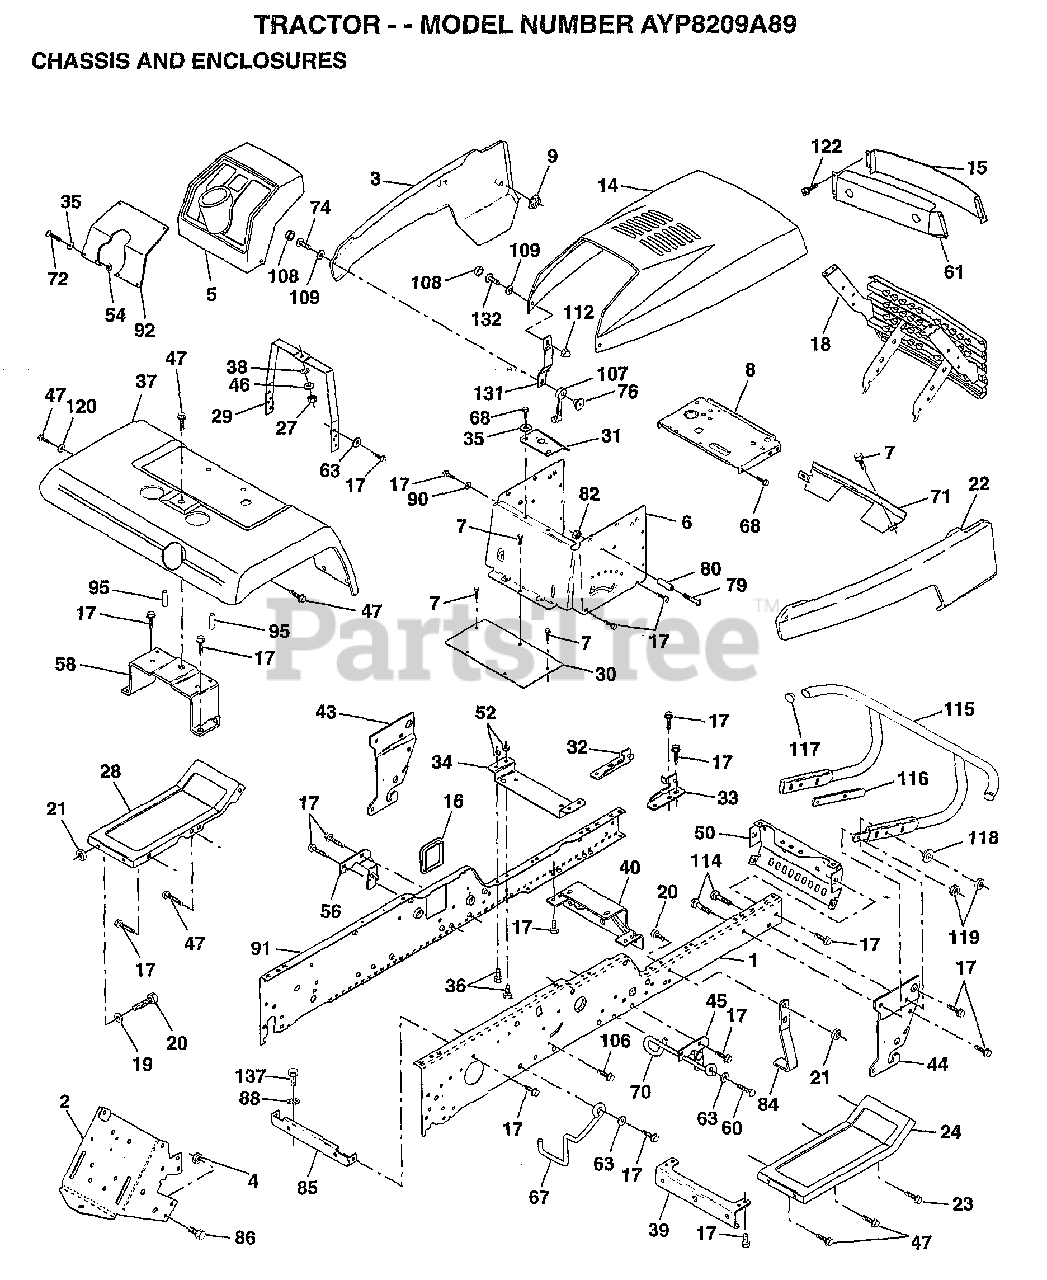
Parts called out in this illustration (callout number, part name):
1	"RAIL,FRAME RH"
2	DRAWBAR GT
3	"PANEL,ASM SIDE LH"
4	NUT GTV
5	DASHBOARD BLACK
6	DASH LOWER
7	SCREW
8	SUPPORT.DASH.BTRY
9	PAL NUT LT
14	"HOOD ASM.,PNT"
15	LENS.BAR.CLEAR
16	COVER ACCESS
17	SCREW
19	WASHER
20	BOLT
22	PANEL ASM.SIDE RH
23	SCREW GTV
24	FOOTREST.RH.LT/GT
28	FOOTREST.LT.LT/GT
29	DASH.SUPT.YP/HUSQ
30	SADDLE.SCR.6SP
31	BRKT SUPT 1-PC VG
32	BRACKET ASM FRAME
33	BRACKET ASM FRAME
34	BRACKET.ENG.SUPT.
35	WASHER
36	BOLT
37	"FENDER,RH"
38	LOCKWASHER
39	BRACKET.AXLE.FRT.
40	"BRKT SUPPORT,AXLE"
43	BRACKET.SUS.FT.LH
44	BRACKET.SUS.FT.RH
45	BRACKET.SUSP.RH.
46	WASHER PM
47	SCREW LT
50	"BRKT CHASSIS,FRNT"
56	BRACKET.SUSP.LH.
58	BRKT.ASM.FENDER
60	SCREW
61	BEZEL.ASM.
63	WASHER
67	"GUIDE BELT, T/A"
68	SCREW LT
70	GUIDE.BELT.MID.SP
72	SCREW
74	SCREW
76	WELDNUT
79	SCREW
80	SPACER LT
84	STOP.OVER.CENTER
85	BRACKET.SUPT.TRAN
86	BOLT
88	LOCKWASHER
90	LOCKWASHER
91	"RAIL FRAME,LH"
92	"PLATE DASH,SLKSCR"
95	NUT-PUSH YT
107	HOOD LATCH T
108	SNAP CAP LT
109	WASHER LT
112	ACORN NUT RB
114	BOLT.3/8-14X1.25
115	BUMPER.ASM
116	BRACKET.EXT.BUMP.
117	PLUG.PLASTIC
118	WASHER
120	WASHER HYT
122	SCREW.HEX.WS.HD
131	BKT.SPT.HOOD/PANL
132	SCREW.10-24X3/8.
137	BOLT
